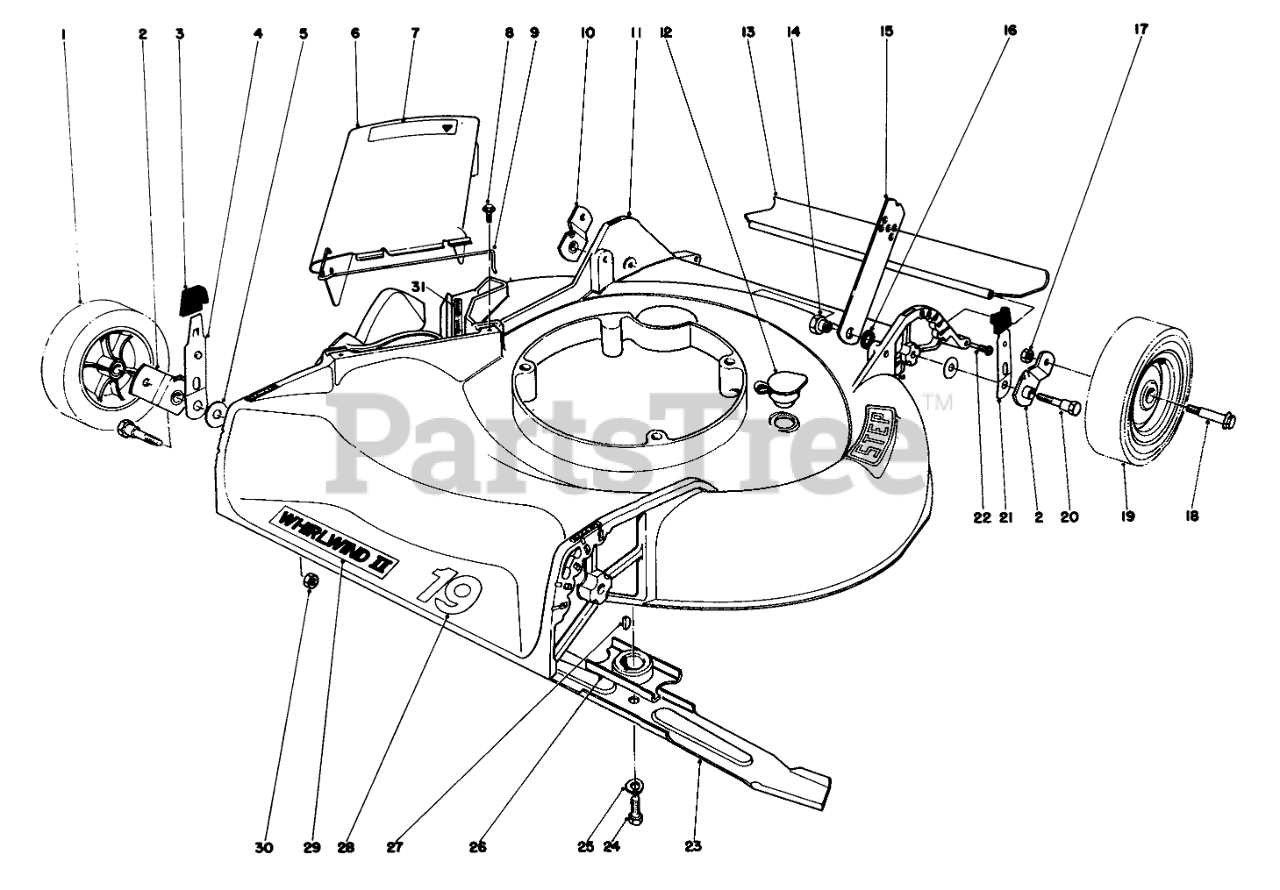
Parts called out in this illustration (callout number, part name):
1	Wheel Assembly
2	Pivot Arm
3	KNOB-ARM
4	SPRING ARM ASM
5	WASHER-PIVOT
6	Deflector Assembly (Incl.Ref. #7 & 9)
7	Caution Decal
8	Screw Special
9	SPRING HINGE
10	Pivot Arm
11	Housing
12	WASHOUT PLUG
13	SHIELD - TRAILING
14	HANDLE PIVOT NUT
15	Handle Latch
16	HANDLE LATCH SPACER
17	Nut
19	Wheel & Tire Assembly (Model No. 16067 & 16155)
20	Jack Nut
21	SPRING ARM ASM
22	SAFTEY SHIELD SCREW
23	Blade
24	SPECIAL SCREW
25	WASHER-LOCK
26	Blade Retailer
27	KEY-WOODRUFF
28	Decal-19"
29	Decal Whirlwind
30	Nut
31	Decal
